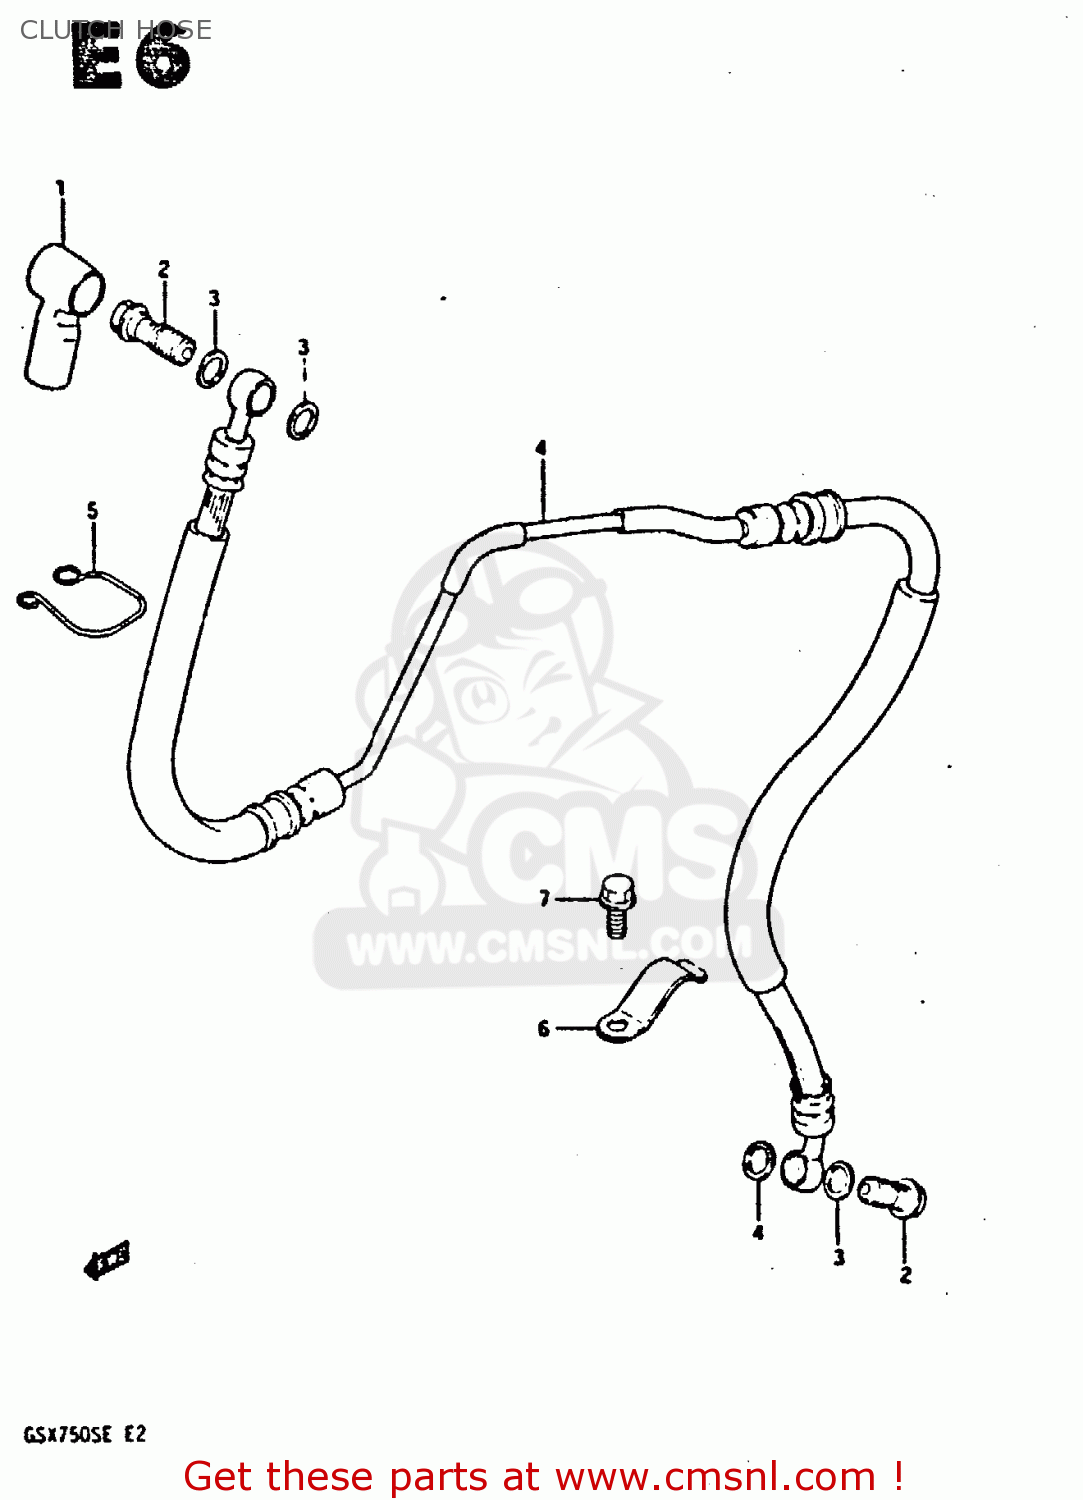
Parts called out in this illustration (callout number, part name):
1	BOOT,MASTER CYLINDER
2	BOLT UNION
3	WASHER(10X15X1.5)
4	HOSE,CLUTCH
5	GUIDE,CABLE/HARNESS
6	CLAMP
7	BOLT 6X12
